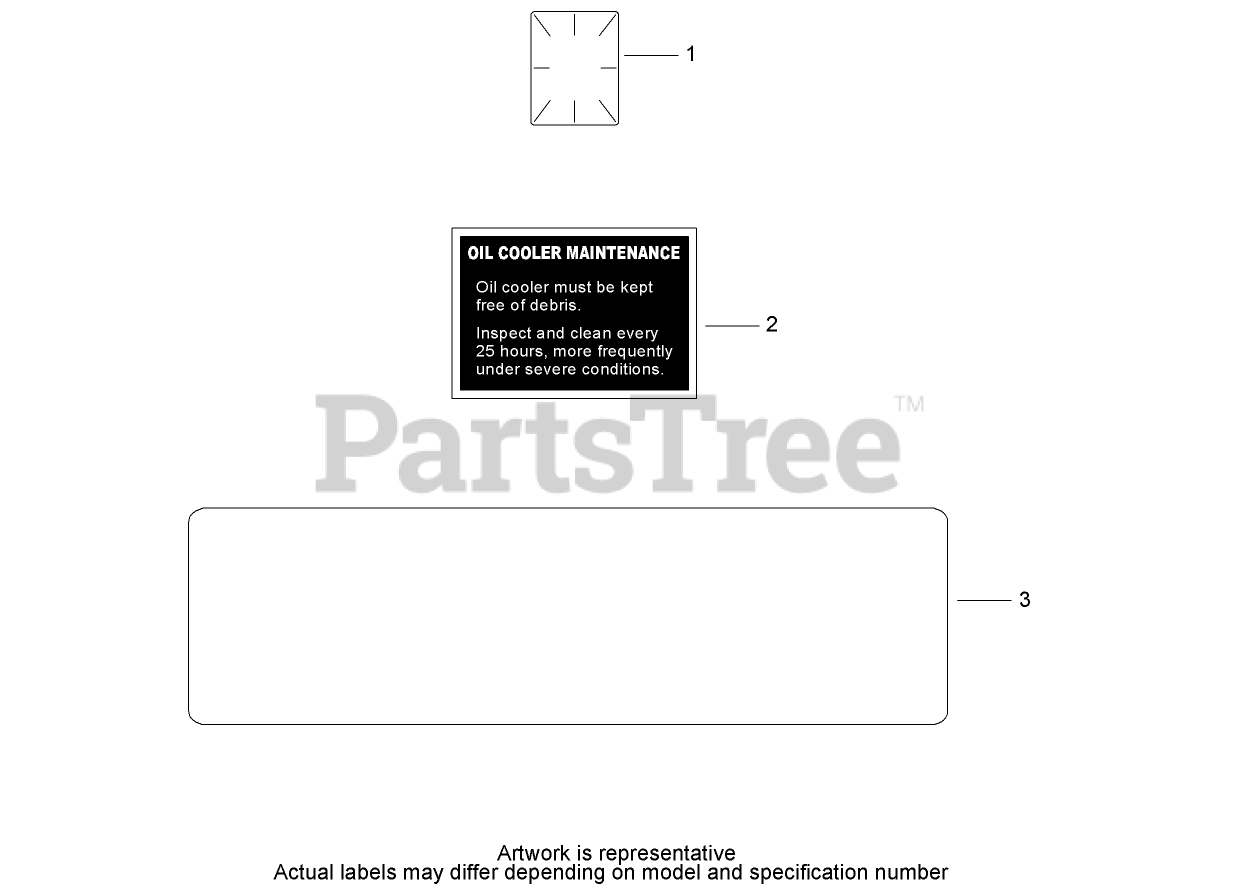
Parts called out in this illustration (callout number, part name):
1	DECAL-LAMINATE, CLEAR
2	DECAL-COOLER, OIL
3	Decal-25 HP
